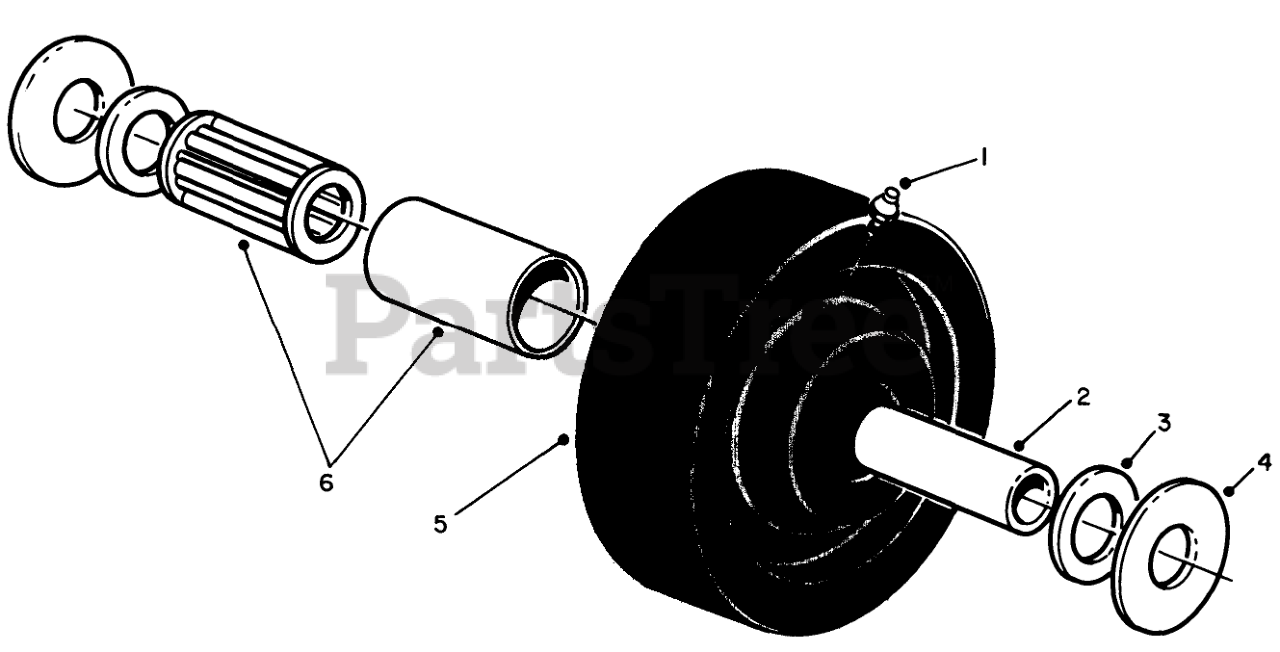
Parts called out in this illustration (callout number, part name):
1	FITTING-GREASE
2	SPANNER BUSHING
3	BEARING RETAINER
4	THRUST WASHER
5	Wheel
6	ROLLER BEARING
